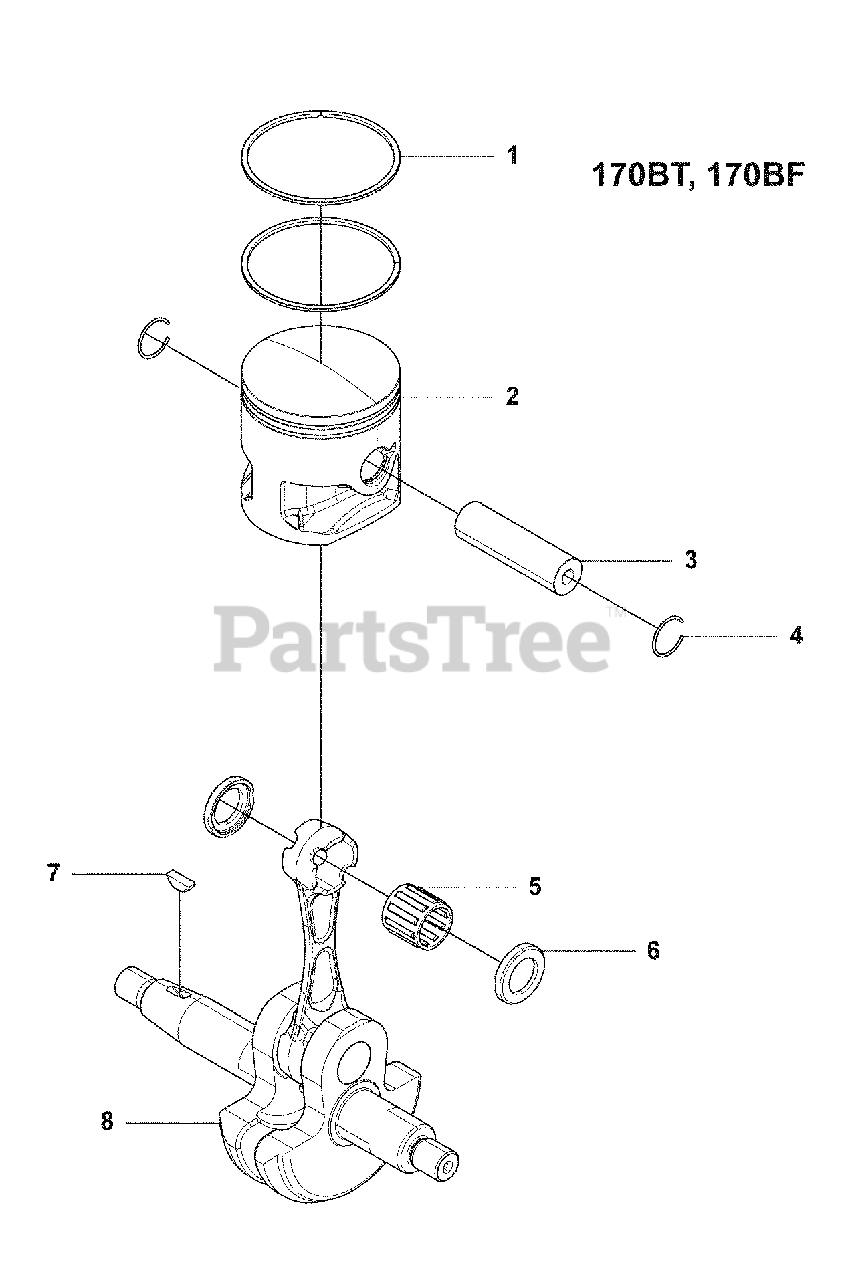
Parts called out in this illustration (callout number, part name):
4	Snap Ring
5	Bearing
6	Washer
7	Flywheel Key
8	Shaft, Comp
